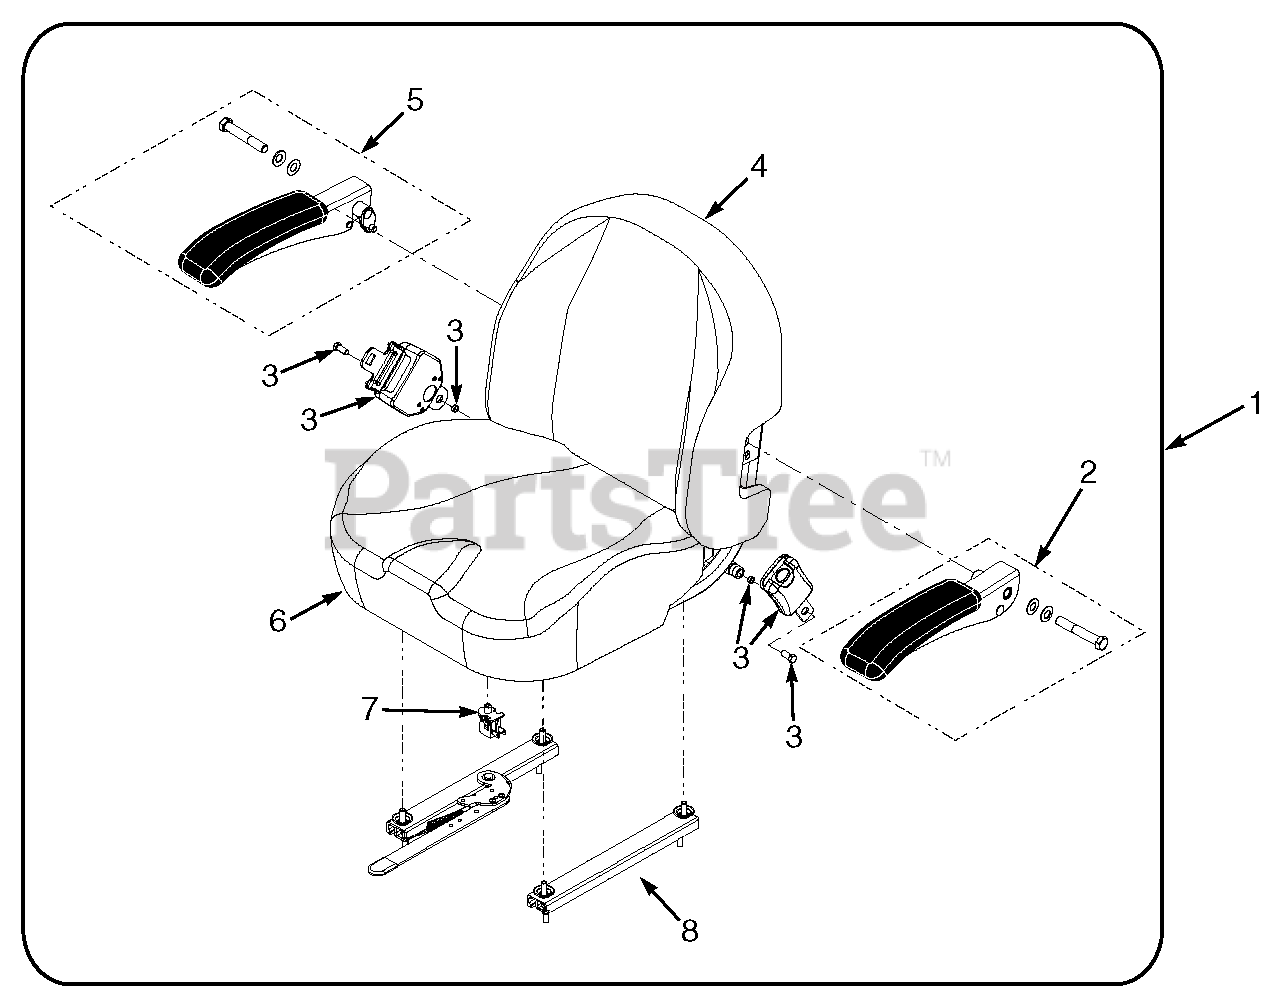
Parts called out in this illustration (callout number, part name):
1	Seat Assembly
2	Armrest Kit, LH
3	Seat Belt Kit
4	Back Cover
5	Armrest Kit, RH
6	Cover, Seat Cushion
7	Seat Switch
8	Track Kit
